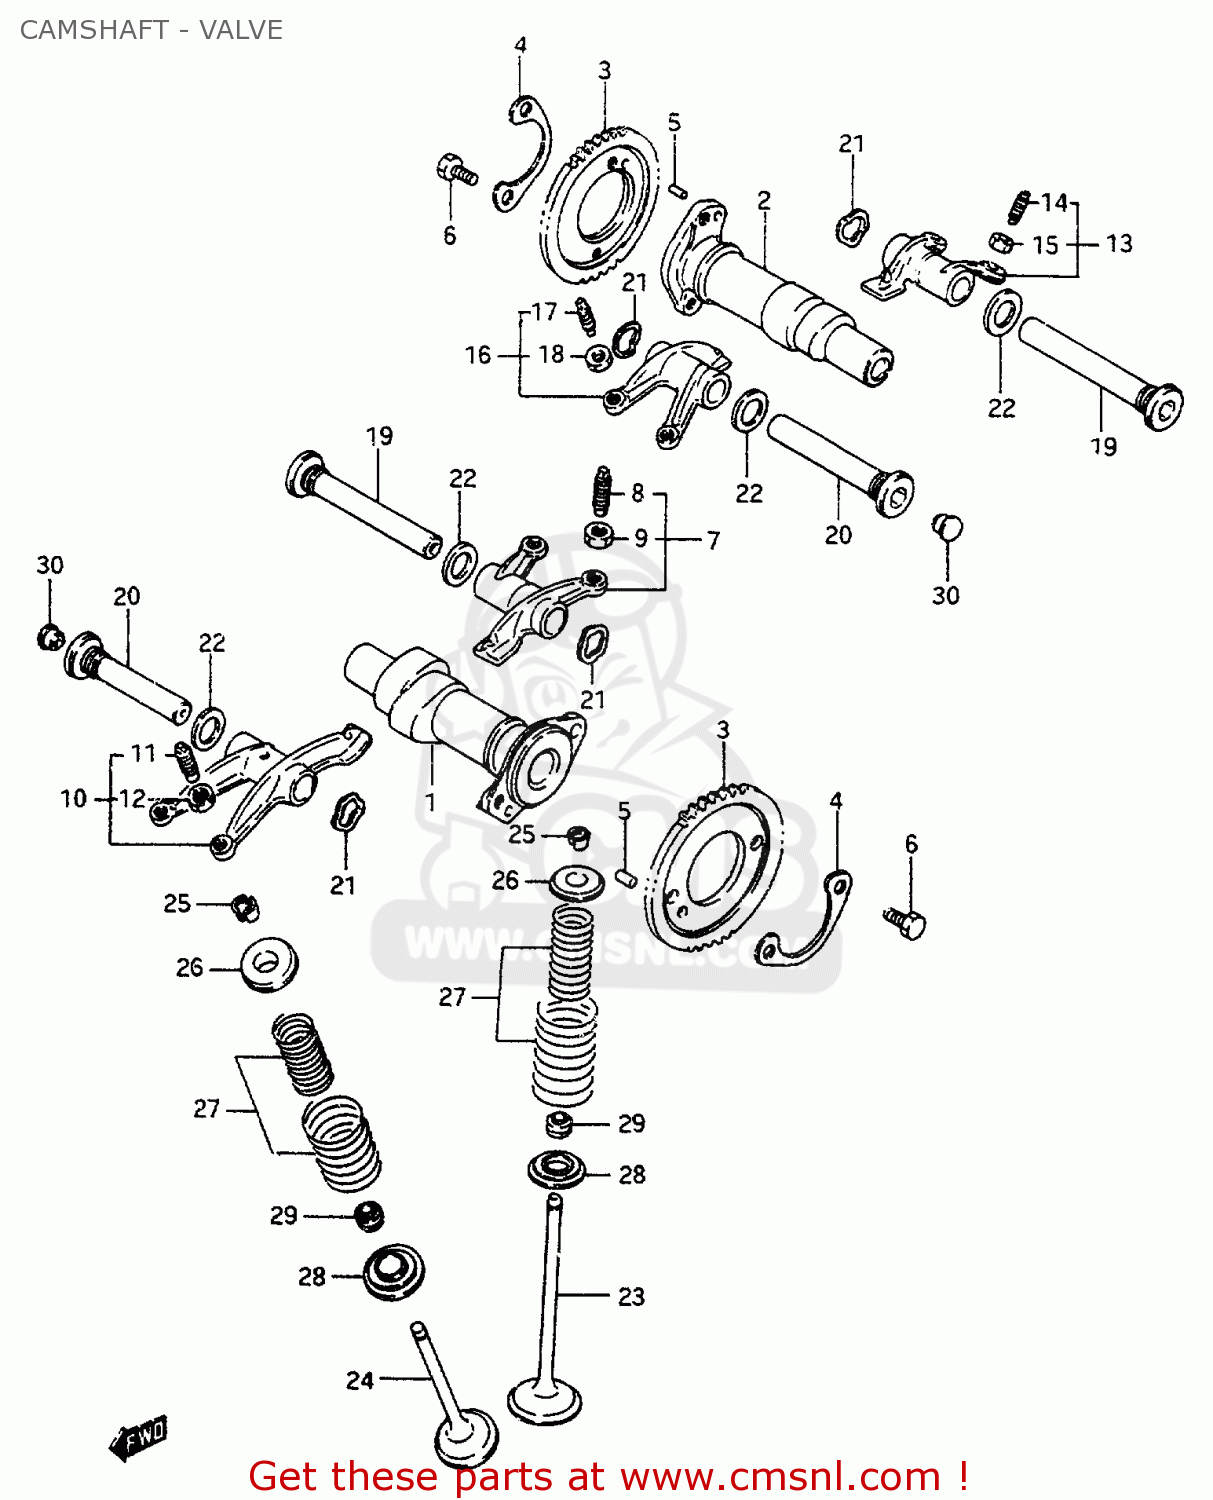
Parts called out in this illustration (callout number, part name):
1	CAMSHAFT,FR
2	CAMSHAFT,RR
3	SPROCKET,CAMSHAFT(NT:42)
4	WASHER,CAM CHAIN SPROCKET
5	PIN
6	BOLT(6X12.5)
7	ARM,INTAKE VALVE ROCKER FR
8	SCREW,TAPPET ADJUSTING
9	NUT,ADJUSTING SCREW
10	ARM,EXHAUST VALVE ROCKER FR
11	SCREW,TAPPET ADJUSTING
12	NUT,ADJUSTING SCREW
13	ARM,INTAKE VALVE ROCKER RR
14	SCREW,TAPPET ADJUSTING
15	NUT,ADJUSTING SCREW
16	ARM,EXHAUST VALVE ROCKER RR
17	SCREW,TAPPET ADJUSTING
18	NUT,ADJUSTING SCREW
19	SHAFT,INTAKE VALVE ROCKER ARM
20	SHAFT,EXHAUST VALVE ROCKER ARM
21	WASHER
22	GASKET(14X19.2X2) (NAS)
23	VALVE,INTAKE
24	VALVE,EXHAUST
25	COTTER,VALVE
26	RETAINER,VALVE SPRING
27	SPRING SET,VALVE
28	SEAT,VALVE SPRING
29	SEAL,OIL(5.5X11X8.2)
30	CAP(OD:12)
